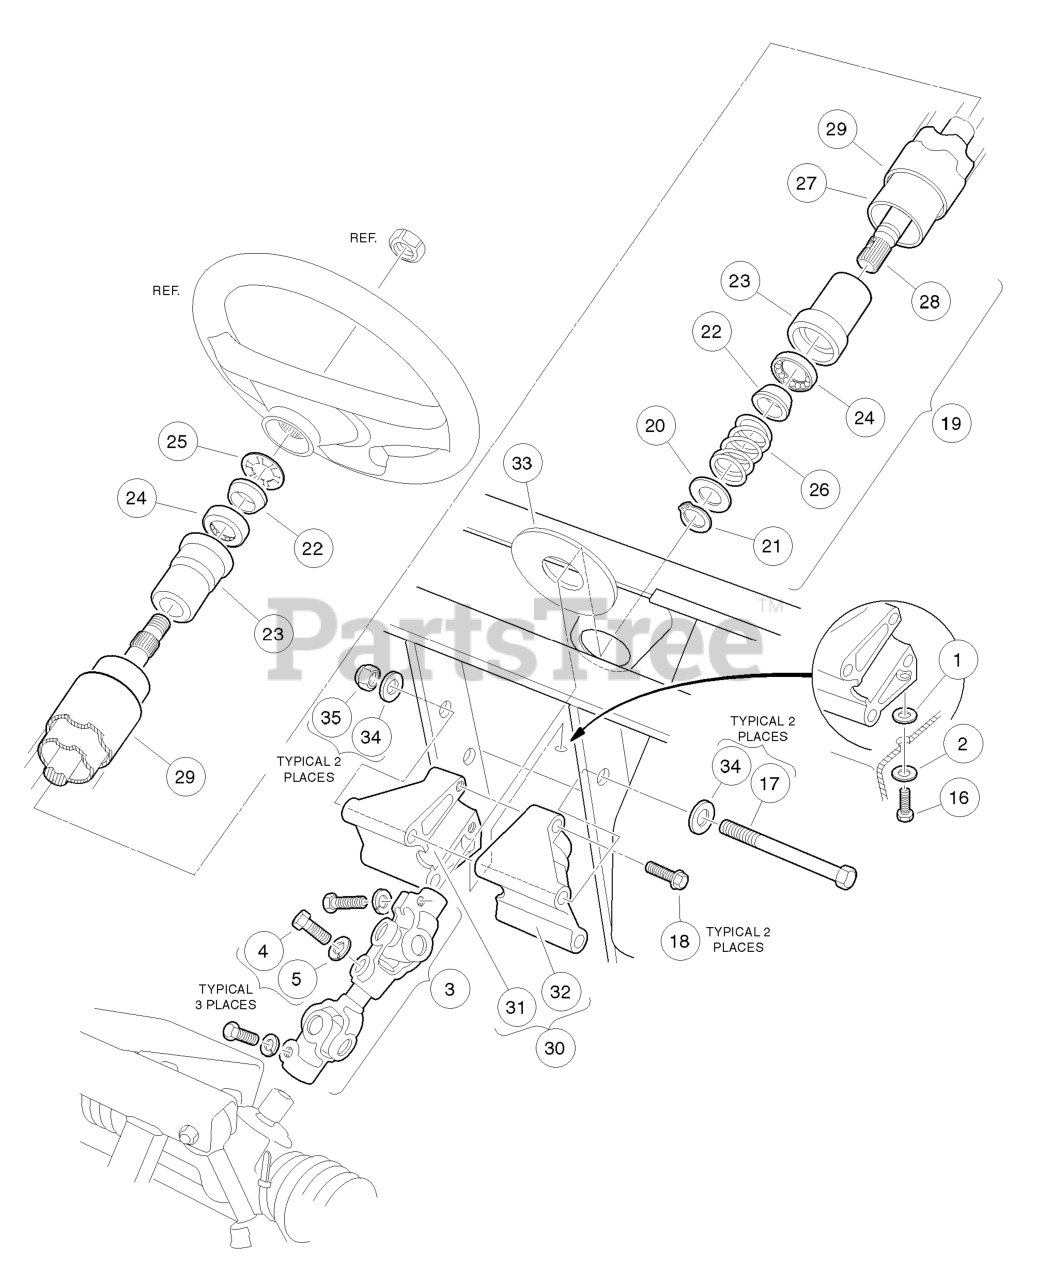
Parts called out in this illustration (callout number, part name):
1	WASHER, 5/16 TYPE B FLAT
2	WASHER, 5/16 FLAT
3	INTERMEDIATE STEERING SHAFT
4	HEX HEAD BOLT, 8MM X 1.25 - 30
5	LOCKWASHER, 5/16 SPLIT
7	DUST COVER
9	WEDGE MOLDED
10	SEAT, PLASTIC BEARING
11	SEAL, BEARING
12	SPACER, SHAFT
13	BEARING ASSY STEERING SHAFT
14	RING, RETAINING
15	SPRING, STEERING SHAFT COMP
17	SCREW, 3/8-16 X 7.00 HEX CAP
18	SCREW, 5/16-18 THRD FORMING
19	STEERING SHAFT ASSEMBLY
22	WEDGE MOLDED
23	SEAT, PLASTIC BEARING
24	BEARING ASSY STEERING SHAFT
25	RING, RETAINING
26	SPRING, STEERING SHAFT COMP
27	COLUMN, LIMO ALUMINUM STEERING
28	SHAFT STEERING COLUMN
29	TUBE COVER STEERING COL-LIMO
30	STEERING COLUMN MTG BRKT KIT
31	Bracket, RH Steering Column Mount
32	Bracket, LH Steering column mount
33	BOOT, STEERING COLUMN ROUND
34	WASHER, 3/8 FLAT
35	LOCKNUT, 3/8-16 HEX
